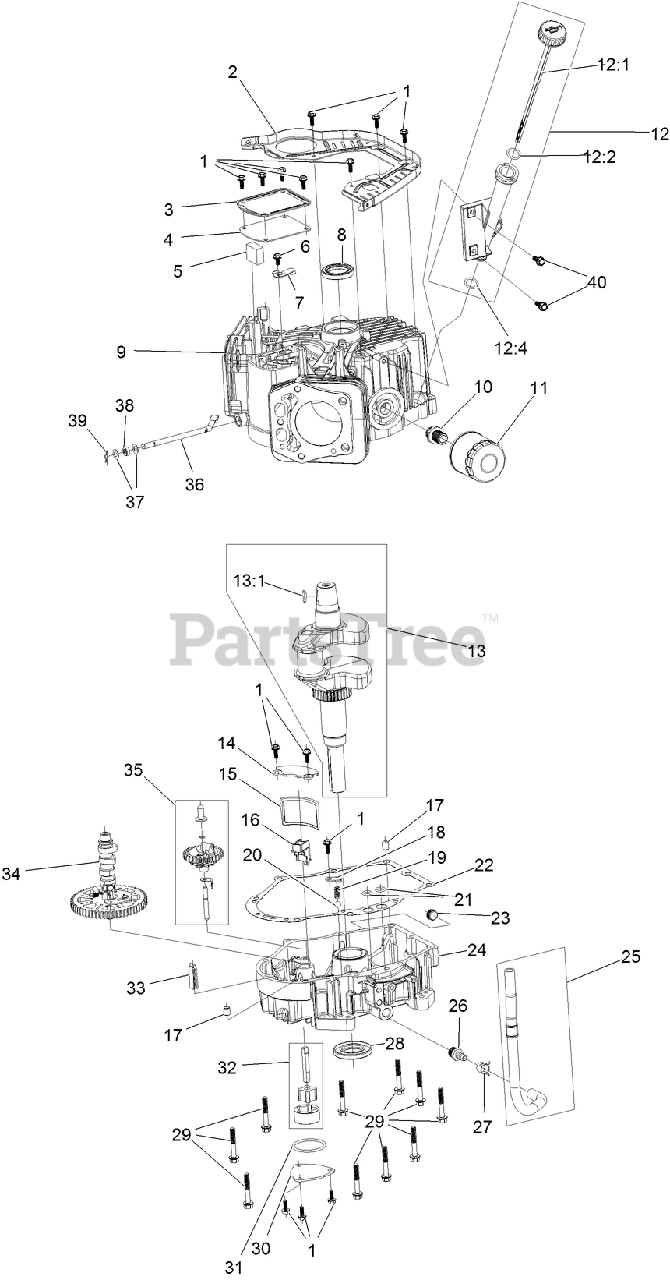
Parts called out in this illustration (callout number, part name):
1	SCREW-HHF
2	BAFFLE
3	COVER-BREATHER
4	GASKET-BREATHER
5	FILTER-BREATHER
6	SCREW-HHF
7	VALVE-BREATHER
8	SEAL-OIL
9	CRANKCASE
10	ADAPTOR-FILTER, OIL
11	FILTER-OIL
12	OIL TUBE ASM
12:1	DIPSTICK
12:2	O-RING
12:4	O-RING
13	CRANKSHAFT
13:1	KEY-WOODRUFF
14	COVER-SCREEN, OIL
15	SCREEN-OIL
16	RETAINER-SCREEN
17	PIN-DOWEL
18	PLATE-RETAINER
19	SPRING
20	VALVE-BALL
21	O-RING
22	GASKET-COVER, CRANKCASE
23	Plug-Drain
24	COVER-CRANKCASE
25	OIL DRAIN HOSE ASM
26	FITTING-HOSE
27	CLAMP-HOSE
29	SCREW-HHF
30	COVER-OIL PUMP
31	O-RING
32	OIL PUMP ASM
33	DEFLECTOR-OIL, RUBBER
34	CAMSHAFT
35	GOVERNOR ASM
36	SHAFT-GOVERNOR
37	WASHER-PLAIN
38	SEAL-OIL
39	PIN-HAIR
40	SCREW-HHF
